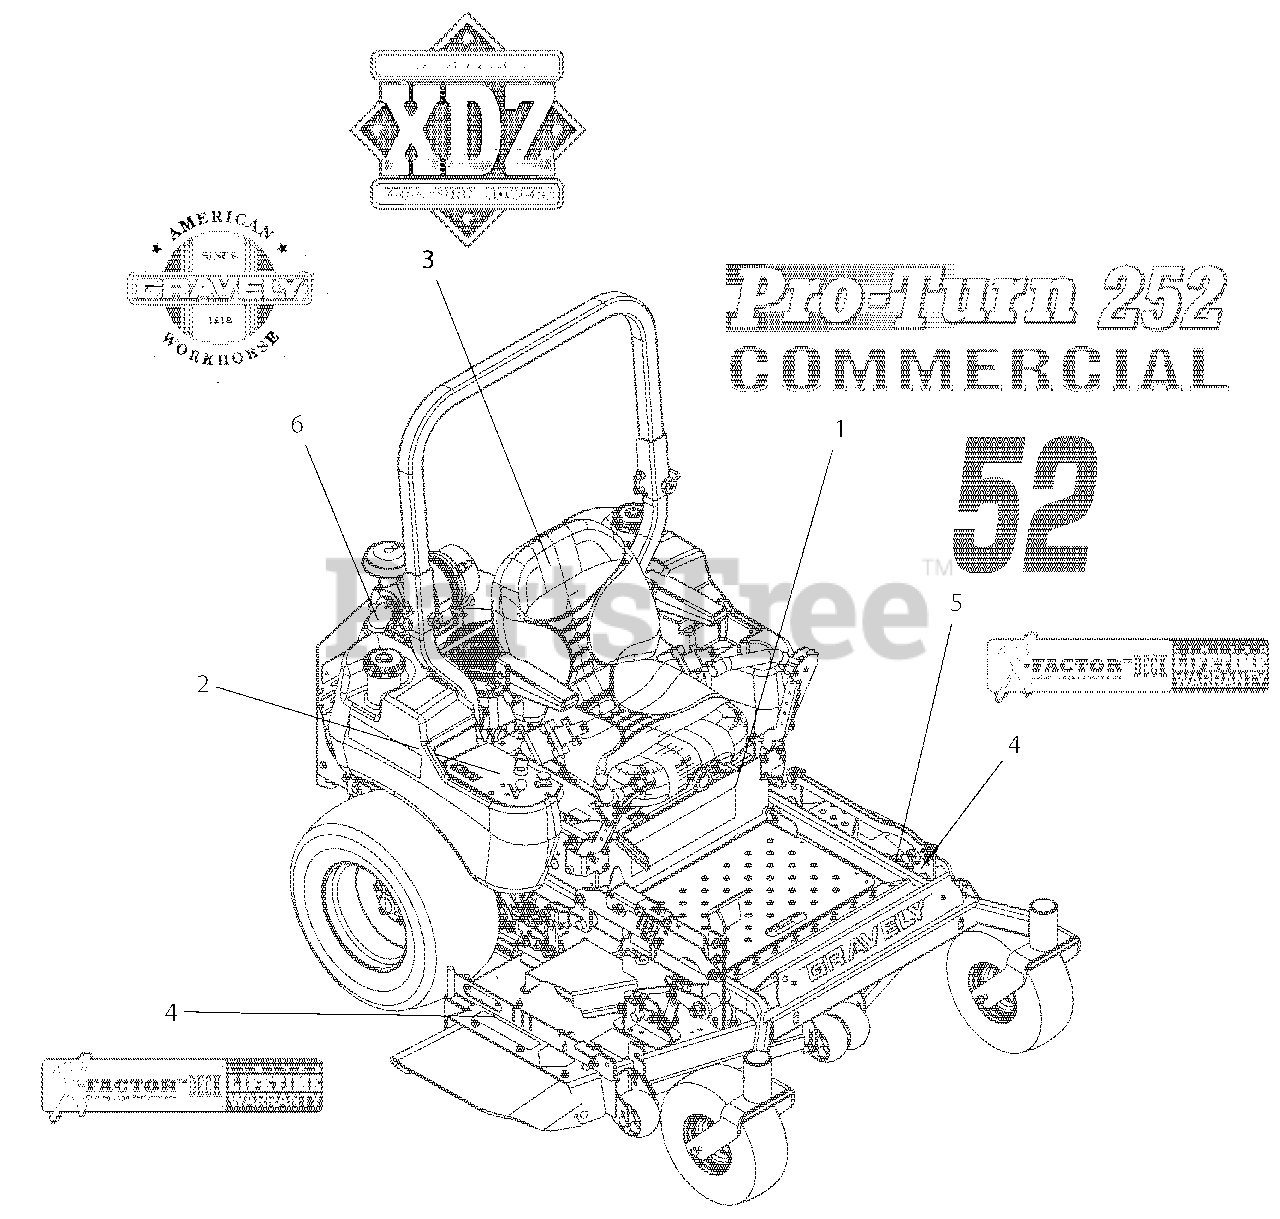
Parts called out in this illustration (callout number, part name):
1	DECAL, PROTURN 252
2	DECAL, CONTROL PANEL EFI
3	DECAL, XDZ
4	DECAL, X-FACTOR DECK
5	DECAL, 52"
6	DECAL, GRAVELY HERITAGE-LARGE
